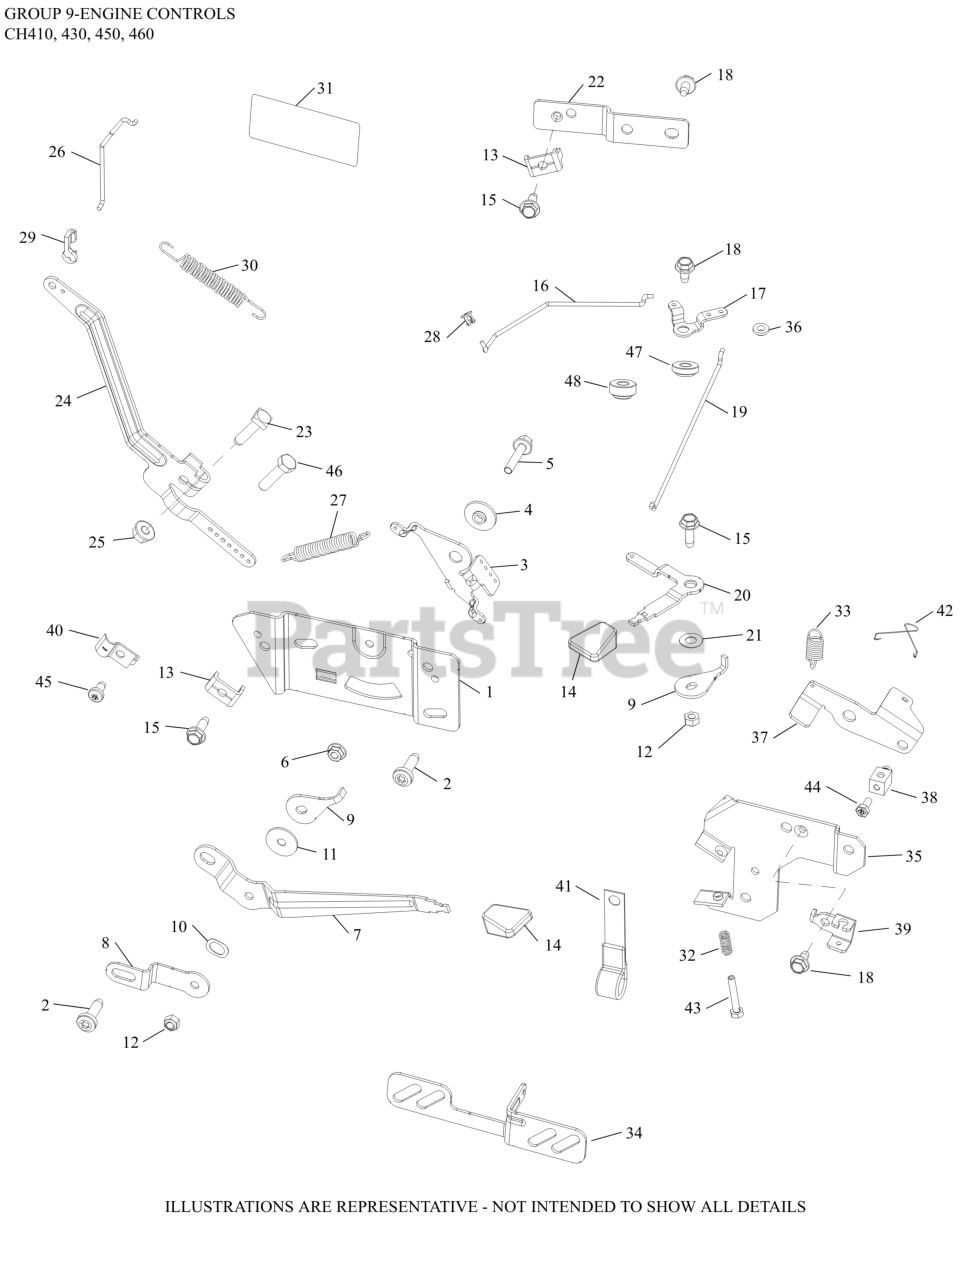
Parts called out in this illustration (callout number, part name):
1	PLATE-DISCONTINUED
2	SCREW, LBD SKT M6x1.0x20-(#25086403S)
4	SPACER, CONTROL ASSEMBLY
5	SCREW, HVY FLG M5X0.8X25
6	NUT, FLG M5X.8
9	TAB-(#DSC)
10	WASHER, SPRING 3/16"
11	WASHER, FLAT 5.5 MM
12	NUT, LOCK M5X.8
13	CLAMP, CABLE-(#2523753S)
14	KNOB-(#DSC)
15	SCREW,FLG THD FRM M5X0.8X16-(#25086398S)
16	LINKAGE, CHOKE
18	SCREW, FLG THD FRM M5X.8X10
20	LEVER, CHOKE
21	WASHER, SPRING 1/4"
22	BRACKET, CHOKE MOUNT
23	SCREW, SQUARE HEAD-(#DSC)
24	LEVER, GOVERNOR
25	NUT, FLG M6X1.0
28	BUSHING, LINKAGE RETAINING
29	BUSHING, THROTTLE LINKAGE
